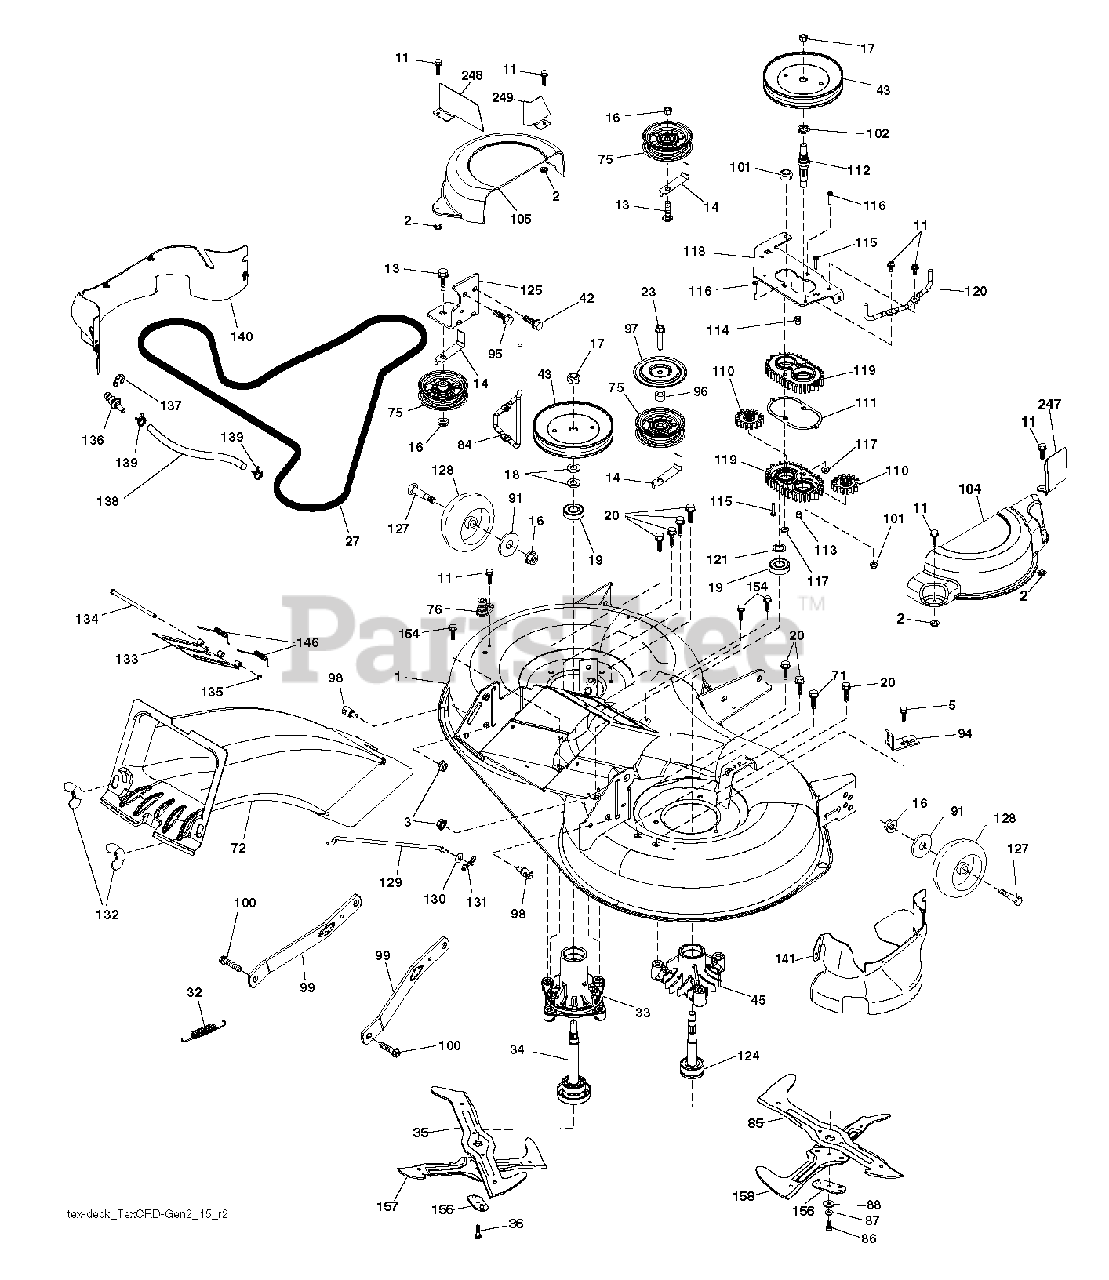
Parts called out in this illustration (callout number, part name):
2	PALNUT 1/4
3	NUT LOCK HEX FLANGE 5/16-18
5	BOLT.5/16HEX.WHS.HD
11	SCREW.1/4-20X5/8
13	BOLT.3/8-16X1.50
14	KEEPER, BELT IDLER
16	NUT LOCK FLG 3/8-16 UNC
17	NUT.FLANGE.LOCK.TOP
18	WASHER.SPACER.MANDREL
20	SCREW, WASHER HEAD
23	SCREW LT
33	HOUSING MANDREL
34	SHAFT.ASM.MDRL.N/GREASE.38
35	BLADE.3N1.LH.CRD
36	BOLT.WASHER.ASM.7/16-2
42	SCREW
45	HOUSING.MANDREL
75	FLAT IDLER PULLEY
85	BLADE.3N1.RH.CRD
87	LOCKWASHER
88	WASHER.BLADE
94	BRKT.CLUTCH.CABLE
95	SCREW, 3/8-16X3/4
98	STUD.FASTNER.W/ANTI-ROTATE
99	ARM.SUSPENSION.MOWER.R
100	BOLT.SHOULDER
102	SPACER BEARING
117	NUT T
127	BOLT.SHOULDER.3/8-16X3-5/8
128	WHEEL. GUAGE RALLY
130	WASHER
131	PIN.COTTER.5/16.BOW TI
132	KNOB.HANDLE.3/8.TRI-POINT.BLAC
135	E-RING.5/16"
137	RING CLIP
